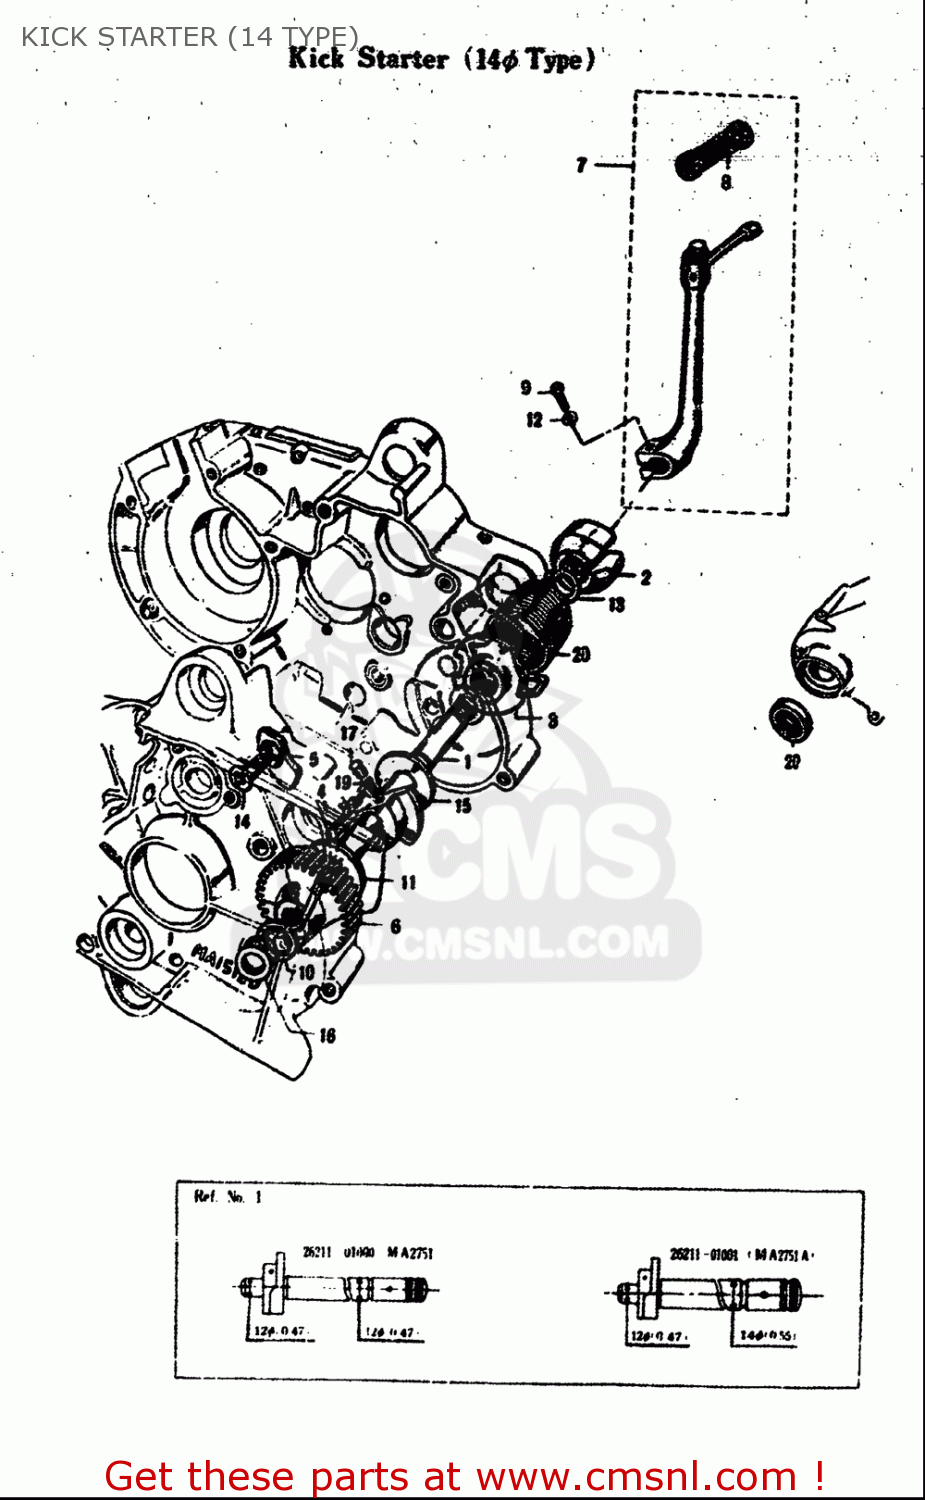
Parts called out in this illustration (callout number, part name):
2	GUIDE,KICK SHAFT SPRING
4	PAWL,KICK STARTER
5	LIFTER,KICK STARTER PAWL
7	LEVER ASSY,KICK STARTER
8	RUBBER,KICK STARTER PEDAL
9	BOLT
10	WASHER,THRUST
11	WASHER
12	WASHER,LOCK
13	CIRCLIP
14	SCREW(6X19)
15	WASHER
18	SEAL,OIL(14X24X6)
19	SPRING
